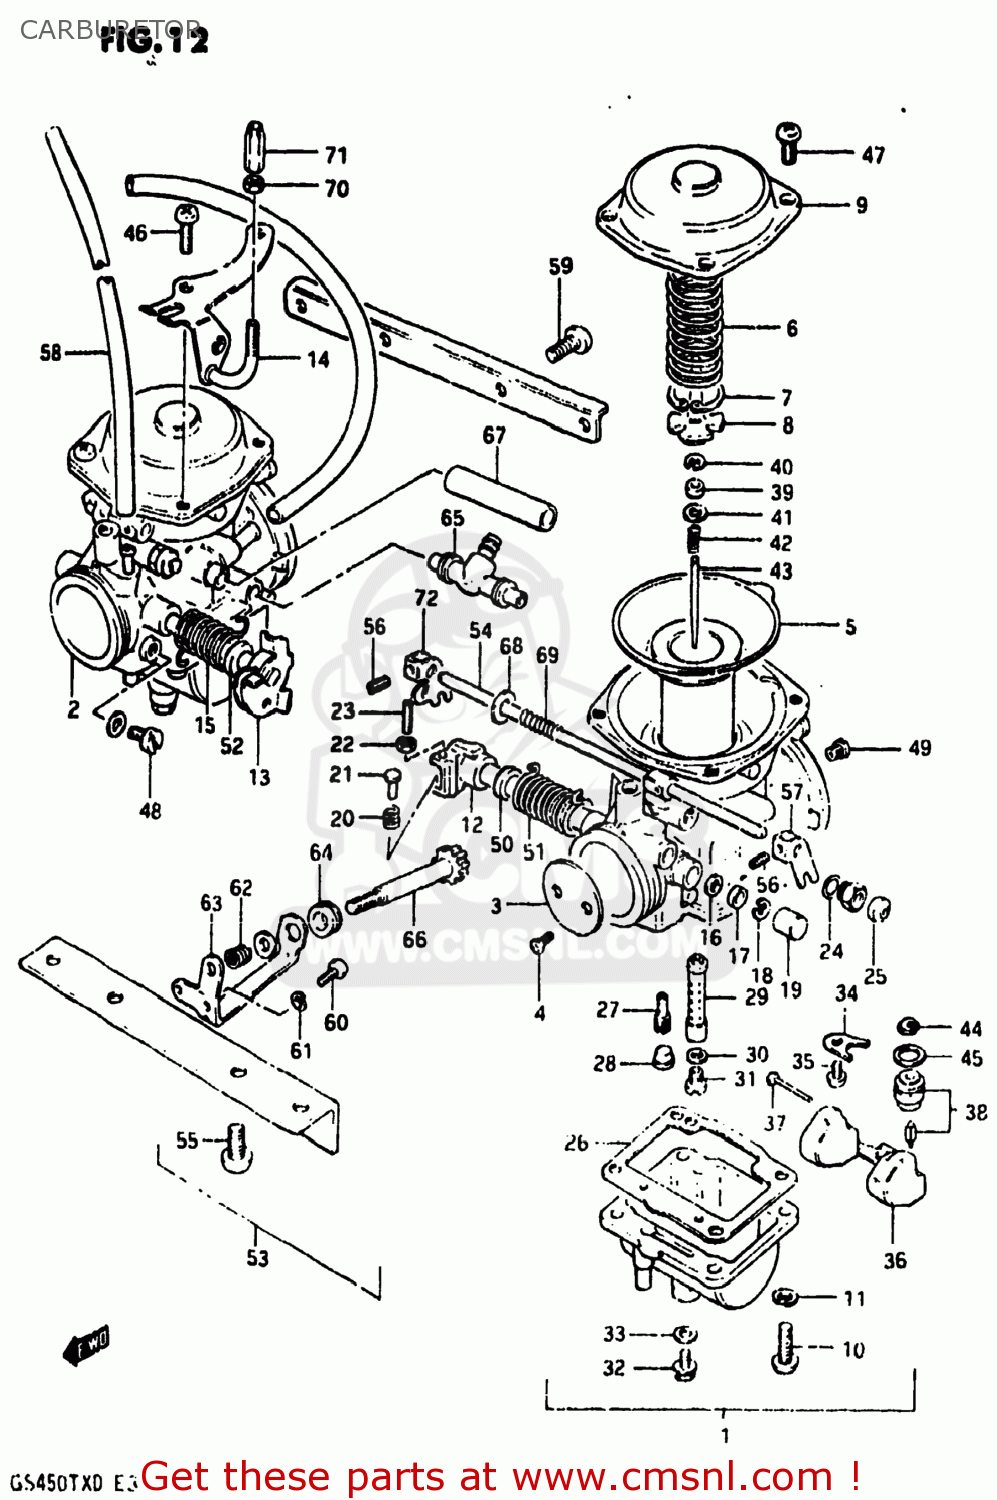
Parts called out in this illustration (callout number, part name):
1	CARBURETOR
2	CARBURETOR ASSEMBLY,RIGHT
3	VALVE,THROTTLE
4	SCREW
5	DIAPHRAGM ASSEMBLY
6	SPRING
7	E RING
8	HOLDER,GUIDE
9	COVER
10	SCREW
11	LOCK WASHER
12	SHAFT ASSEMBLY
13	SHAFT,THROTTLE
14	BRACKET,THROTTLE CABLE
15	SPRING
16	SEAL
17	GASKET,THROTTLE SHAFT (NAS)
18	E RING
19	CAP
20	SPRING
21	PIN,THROTTLE LEVER
22	NUT
23	SCREW
24	O RING
25	CAP,STARTER VALVE
26	GASKET,FLOAT CHAMBER (NAS)
27	JET,PILOT(45)
28	PLUG,NEEDLE JET
29	JET,NEEDLE
30	WASHER,NEEDLE NOZZLE
31	JET,MAIN(115)
32	PLUG,DRAIN
33	GASKET (NAS)
34	PLATE,NEEDLE VALVE FITING
35	SCREW 4X6
36	FLOAT
37	PIN,FLOAT
38	VALVE ASSEMBLY,NEEDLE
39	RING
40	E-RING
41	WASHER,JET NEEDLE
42	SPRING
43	NEEDLE JET
44	FILTER
45	O-RING,NEEDLE VALVE
46	SCREW
47	SCREW
48	SCREW
49	JET,AIR
50	SPACER,THROTTLE SHAFT
51	SPRING
52	SPACER,THROTTLE SHAFT
53	FLANGE ASSEMBLY,CARBURETOR
54	SHAFT,STARTER
55	SCREW 6X12
56	SCREW
57	LEVER
58	HOSE
59	SCREW
60	SCREW
61	LOCK WASHER
62	SPRING,THROTTLE ADJUST
63	BRACKET,THROTTLE ADJUST
64	CAP,RUBBER
65	NIPPLE,CARBURETOR
66	SCREW
67	HOSE
68	WASHER,STARTER PLUNGER
69	SPRING,STARTER
70	NUT
71	ADJUSTER
72	LEVER,STARTER
